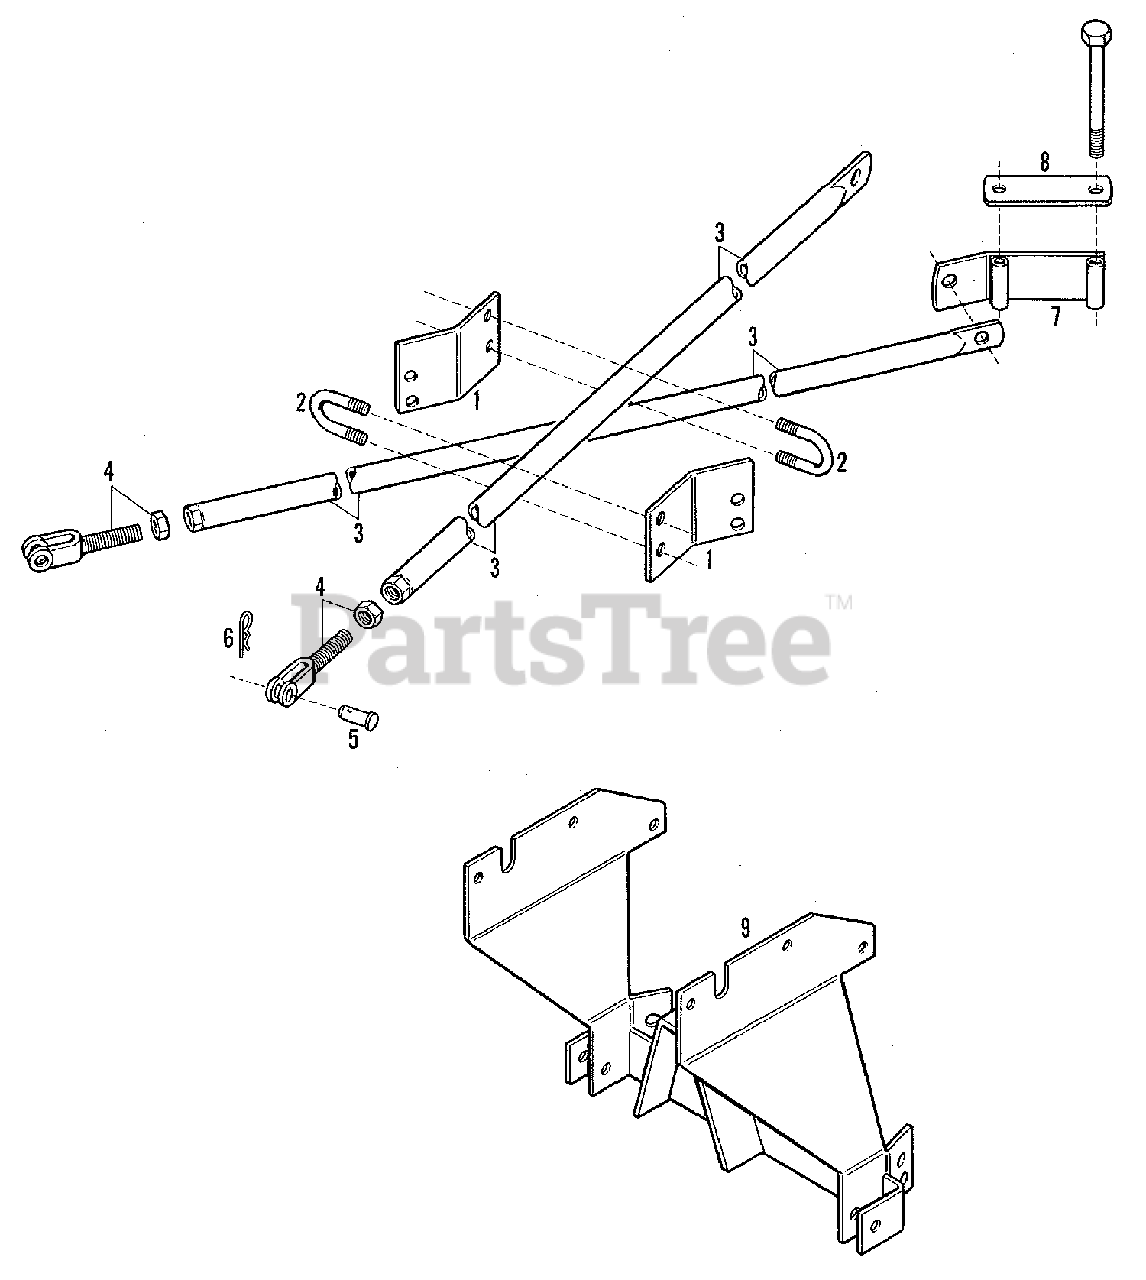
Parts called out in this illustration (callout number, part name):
1	PLATE, Clamp
2	LOCKWASHER, 5/16
2	NUT, 5/16NC
3	TUBE ASSEMBLY
3	CAPSCREW, 1/2NC x 1-1/4
3	LCOKWASHER, 1/2
4	NUT, Jam, 5/8NC
6	CLIP, Hairpin
7	BRACKET ASSEMBLY
8	CAPSCREW, 1/2NC x 7
8	CAPSCREW, 1/2NC x 9 (For Use w/Roll Over Protection Only)
8	LOCKWASHER, 1/2
9	PLATE ASSEMBLY, Side
9	CAPSCREW, 7/16NC x 1-1/4
9	CAPSCREW, 7/16NC x 1-1/2
9	LOCKWASHER, 7/16
9	NUT, 7/16NC
9	CAPSCREW, M12 x 1-1/2 x 40MM (For 4-Wheel Drive)
9	WASHER, Plain, 17/32 x 1-1/4 x 14 GA
9	LOCKWASHER, 12MM (For 4-Wheel Drive)
